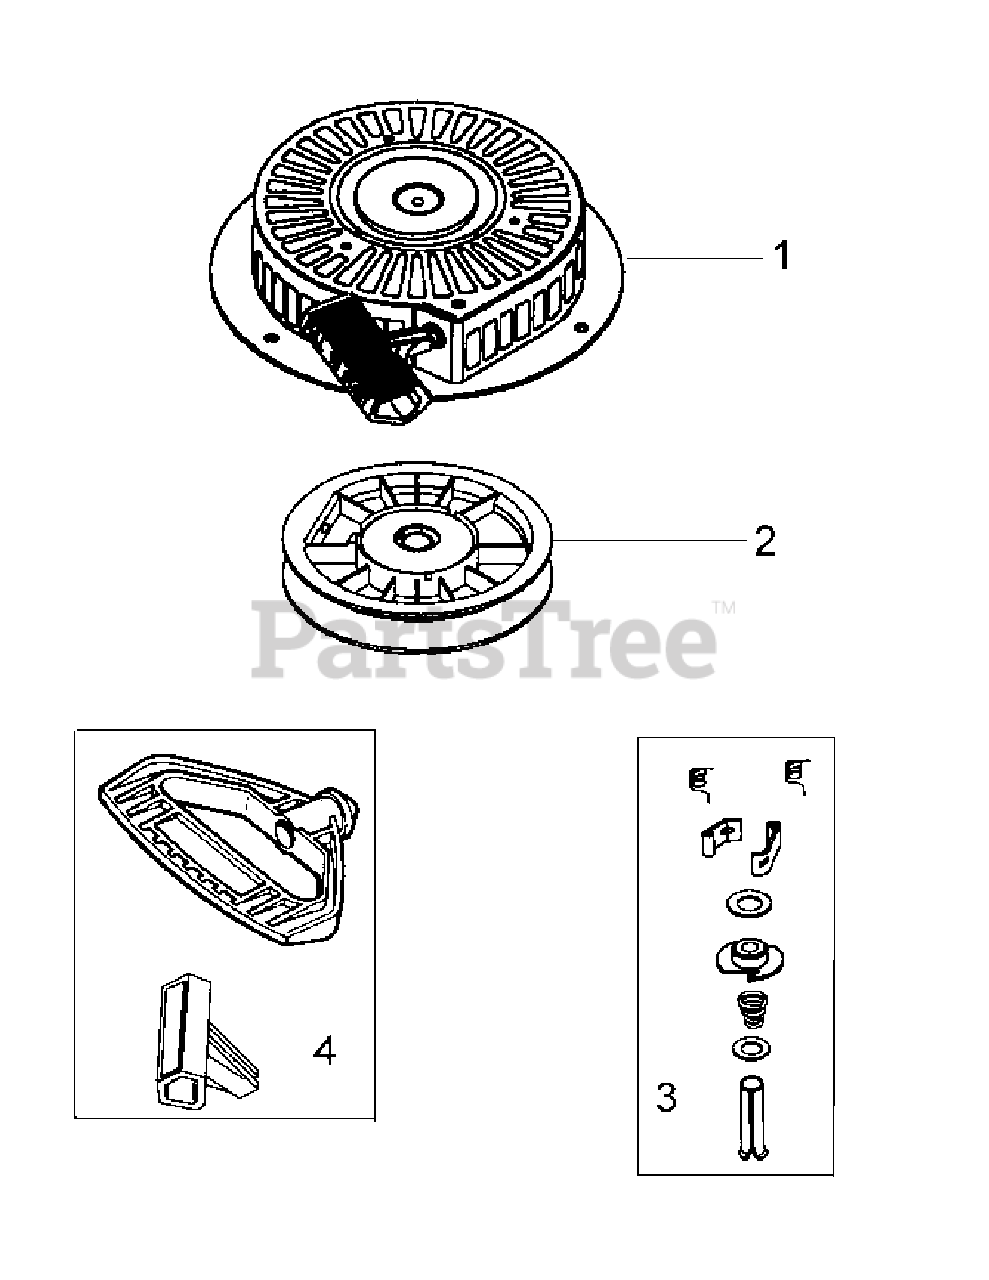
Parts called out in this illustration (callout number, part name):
1	Rewind Starter
2	Pulley & Rewind Spring Assembly
3	Repair Kit
4	Starter Handle
5	98" Starter Rope (cut to length)
